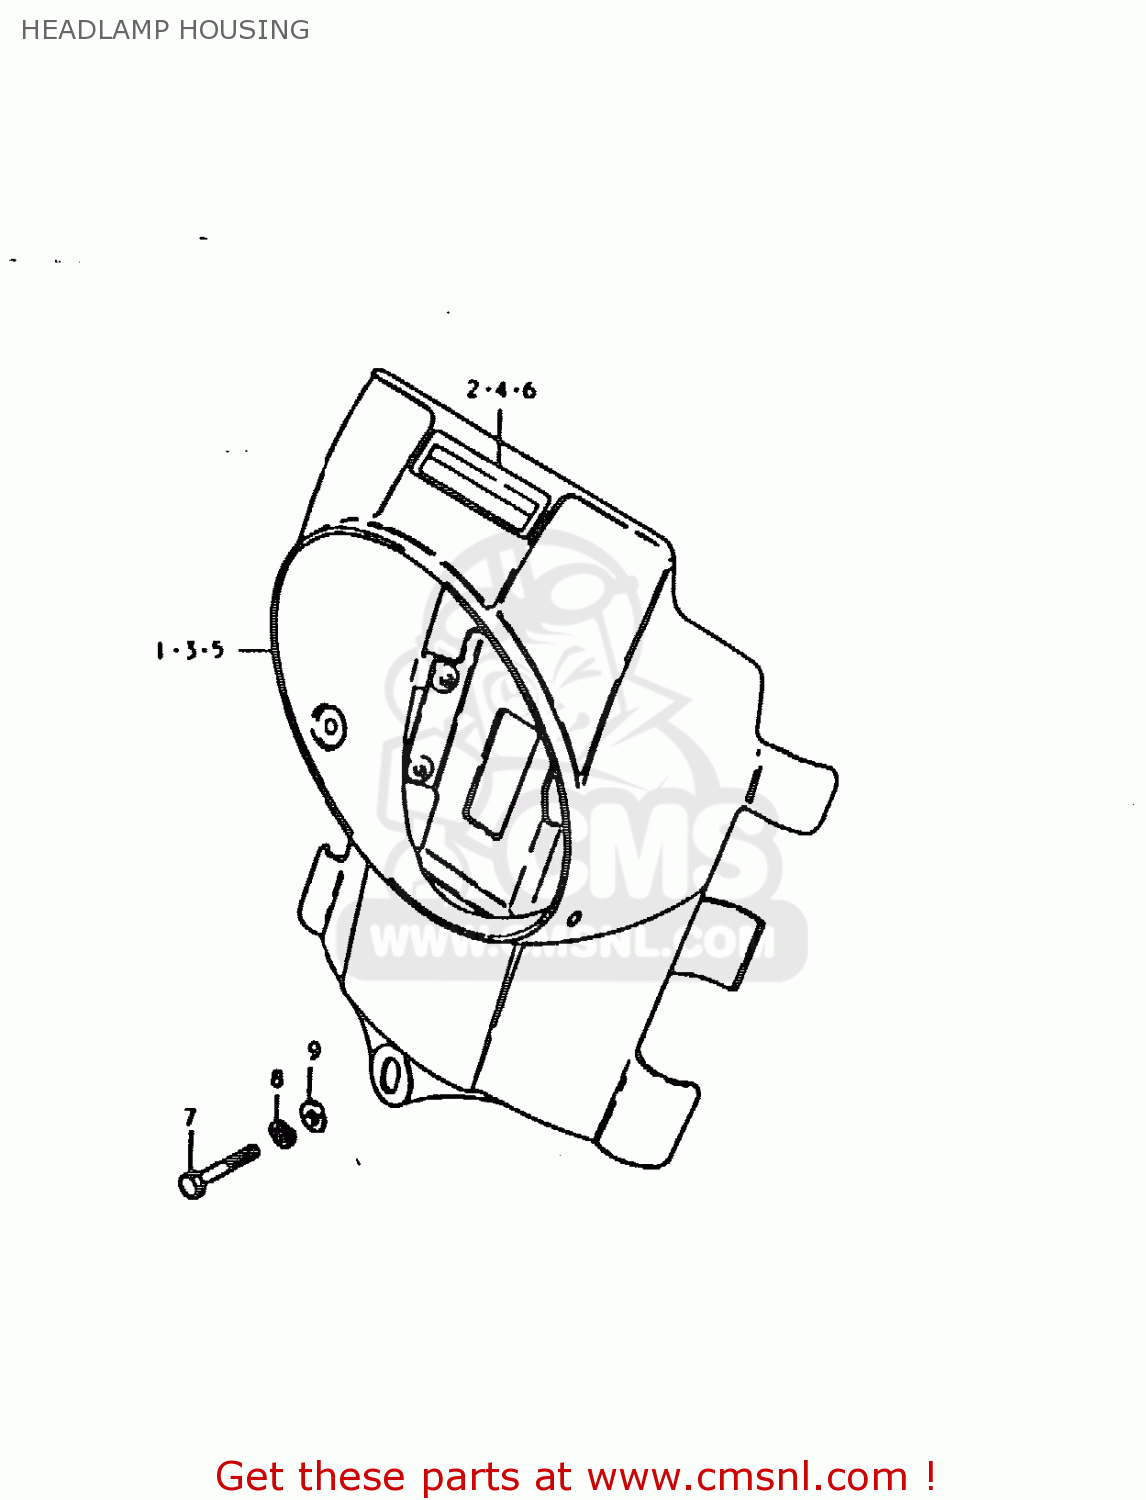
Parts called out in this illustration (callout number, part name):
1	HOUSING, HEADLAMP
2	TAPE, HOUSING
3	HOUSING, HEADLAMP
4	TAPE, HOUSING
5	HOUSING, HEADLAMP
6	TAPE, HOUSING
7	BOLT
8	LOCK WASHER
9	WASHER
